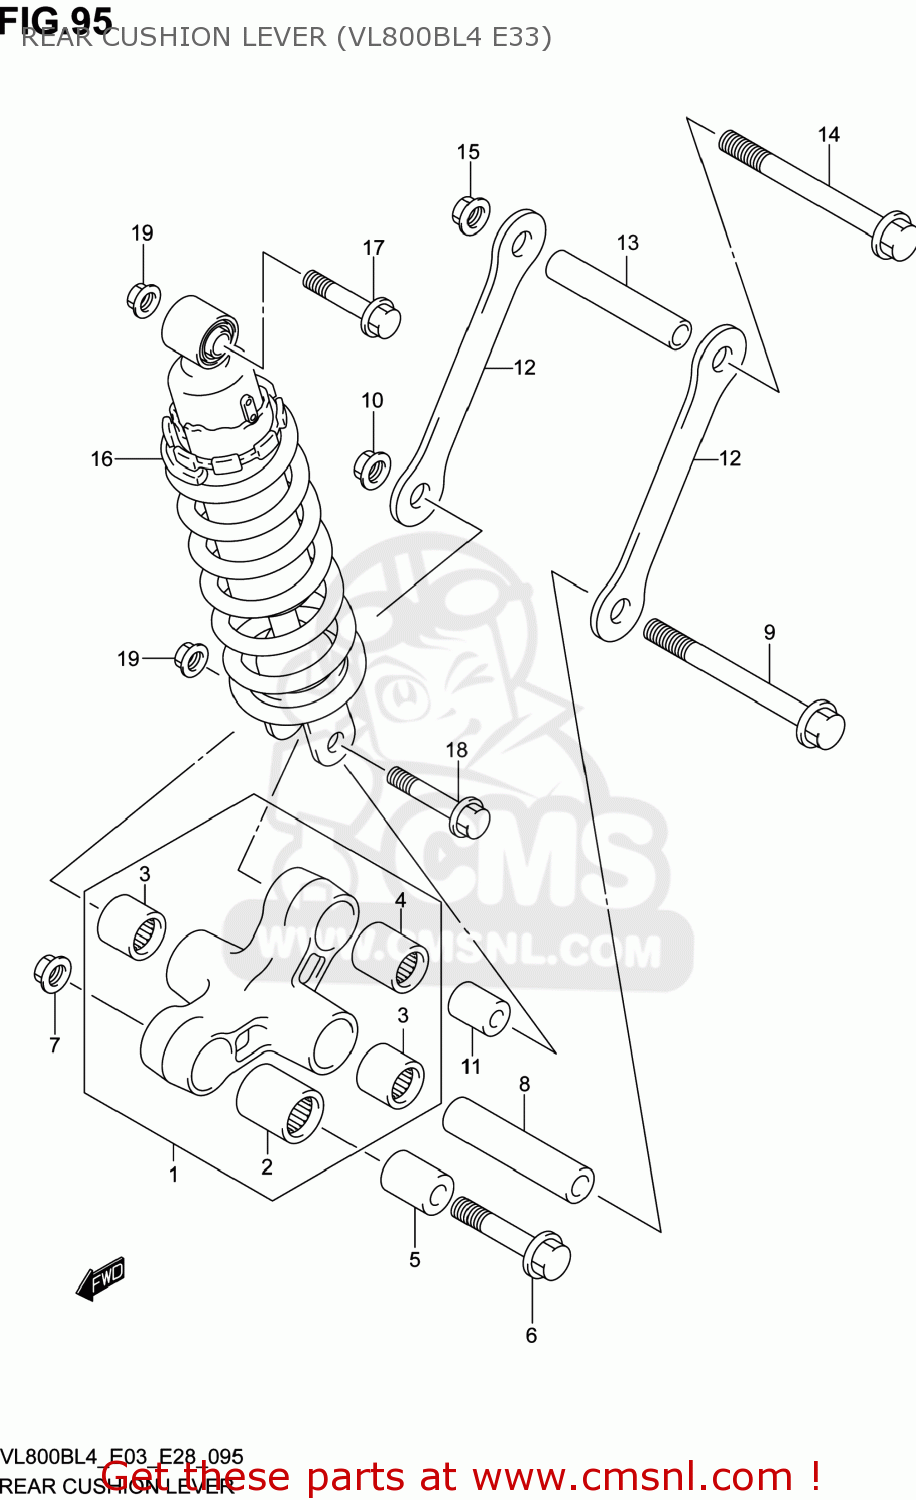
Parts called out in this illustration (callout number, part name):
1	LEVER SET,RR CUSHION
2	BEARING(20X27X30)
3	BEARING(17X24X20)
4	BEARING(17X24X26)
5	SPACER,RR CUSHION LEVER FR
6	BOLT,CUSHION LEVER FR
7	NUT
8	SPACER,RR CUSHION LEVER CTR
9	BOLT,RR CUSHION LEVER CTR
10	NUT
11	SPACER,RR CUSHION LEVER
12	ROD,RR CUSHION
13	SPACER,RR CUSHION LEVER CTR
14	BOLT,RR CUSHION LEVER CTR
15	NUT
16	ABSORBER ASSY,RR SHOCK
17	BOLT(10X50)
18	BOLT(10X54)
19	NUT
